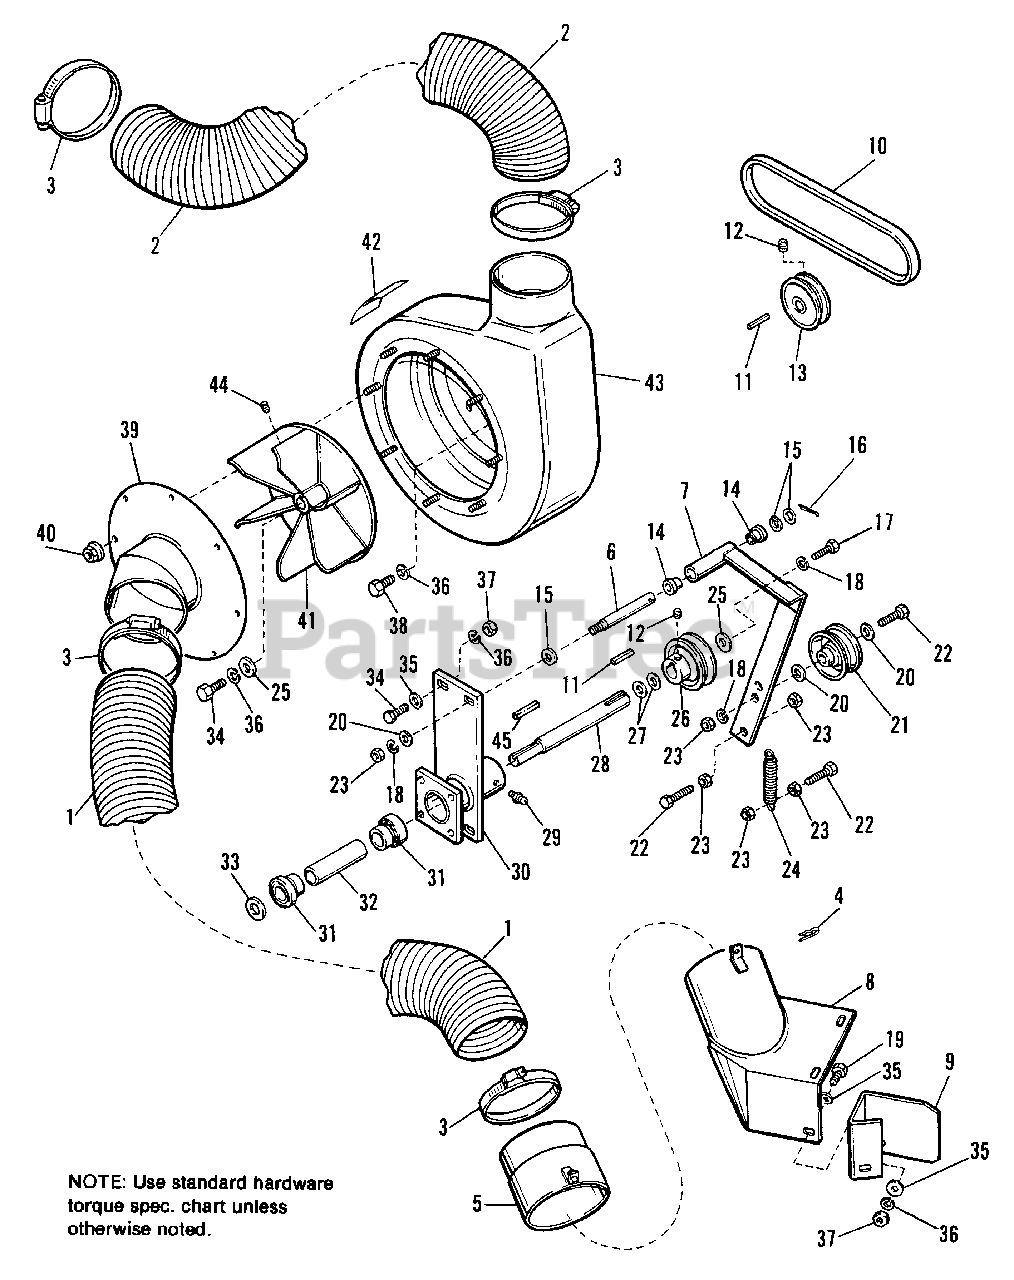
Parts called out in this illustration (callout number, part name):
1	HOSE, Blower Housing, 44"
2	HOSE, Blower to Vac., 33"
3	CLAMP, Hose, 6" Dia.
4	HAIRPIN, Cotter
5	TUBE, Adapter Assy.
6	IDLER SHAFT
7	IDLER ARM ASSY.
8	DISCHARGE BOOT ASSY.
9	ADAPTER, Boot
11	KEY, Sq., 1/4 x 1/4 x 1
12	SETSCREW, Socket Hd., 5/16-18 x 5/16
13	PULLEY, Drive
14	BEARING, Nylon
15	WASHER, Plain
16	PIN, Cotter, 1/8 x 3/4
17	CAPSCREW, 3/8-24 x 1
18	LOCKWASHER, Spring, 3/8
19	CAPSCREW, Hex, 5/16-18 x 3/4
20	WASHER, Plain
21	IDLER PULLEY, Backside
22	CAPSCREW, Hex, 3/8-16 x 1-3/4
23	NUT, Hex, 3/8-16
25	WASHER, Plain
26	V-PULLEY, Drive
27	WASHER, Plain
28	SHAFT, Blower
29	FITTING, Grease
30	FRAME, Housing Assy.
31	BEARING, Ball, 1"
33	WASHER, Plain
34	CAPSCREW
35	WASHER, Plain
36	LOCKWASHER, Spring, 5/16
37	NUT, Hex, 5/16-18
38	CAPSCREW, Hex, 5/16-18 x 3/4
39	INLET, 6"
40	NUT, Whiz Flange, 1/4-20
42	DECAL, Danger
43	BLOWER HOUSING
44	SETSCREW, 3/8-14 x 3/8
45	KEY, 3/16 x 3/16 x 1-1/2
